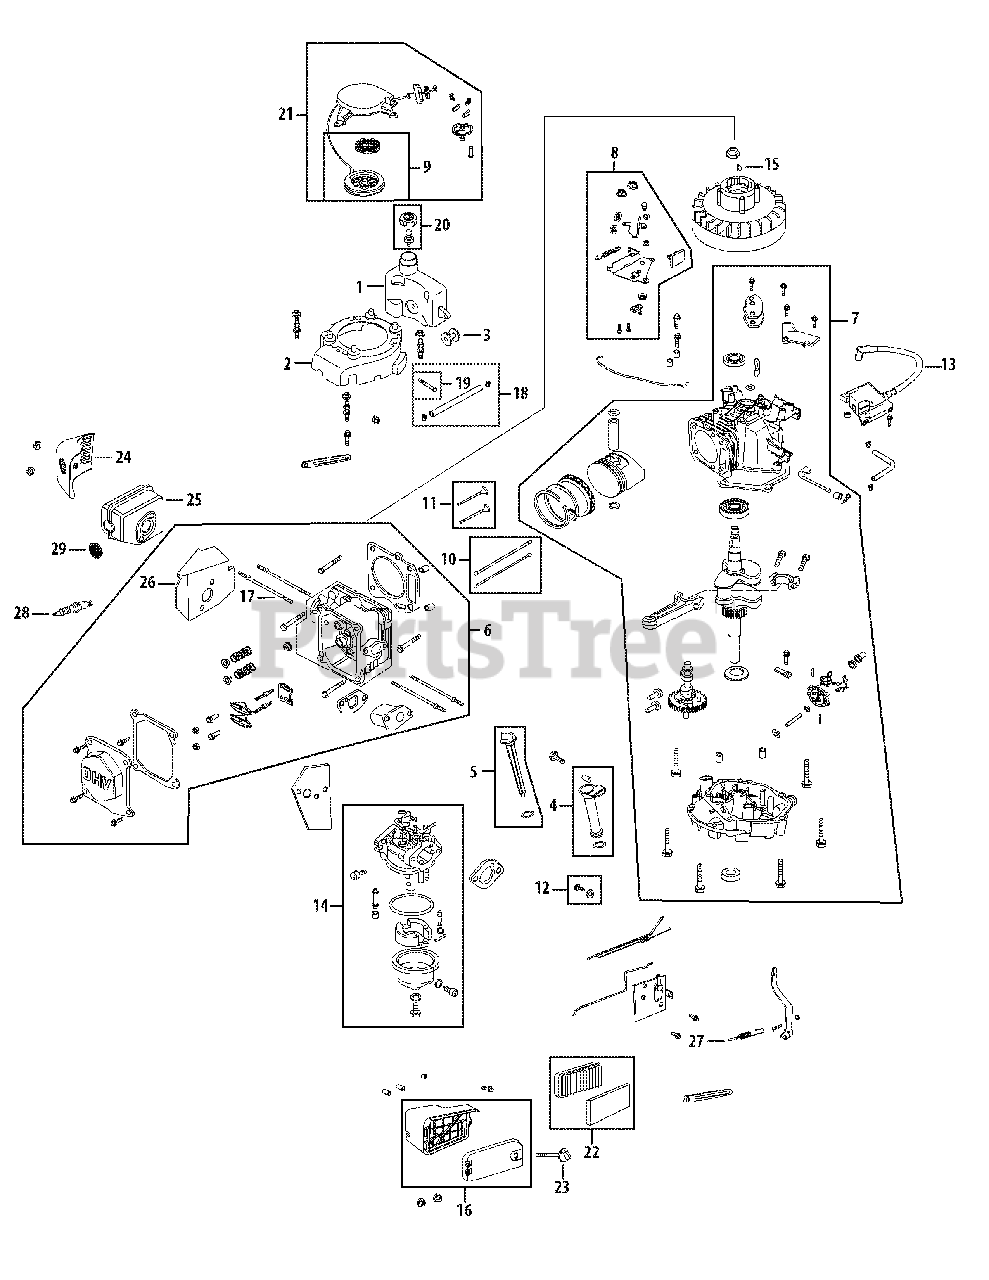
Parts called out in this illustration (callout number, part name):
1	Fuel Tank
2	Flywheel Shroud
3	Rubber Fuel Tank Mounting Washer
4	Oil Filler Tube Assembly
5	Dipstick Assembly
6	Cylinder Head Complete
7	Short Block Assembly
8	Stop Switch and Brake Assembly
9	Recoil Spring and Pulley Assembly
10	Push Rod Kit
11	Valve Kit
12	Oil Drain Plug and Washer Assembly
13	Ignition Coil
14	Carburetor Assembly
15	Flywheel Key
16	Air Cleaner Housing Assembly Complete
17	Muffler Stud Assembly
18	Fuel Line Kit - Inc. hoses, clamps & filter
19	Fuel Filter
20	Fuel Cap Assembly
21	Recoil Starter Assembly
22	Air Cleaner Kit
23	Air Cleaner Thumb Screw
24	Muffler Guard
25	Muffler
26	Muffler Gasket /Heat Shield
27	Governor Return Spring
28	Spark Plug
29	Spark Arrestor
